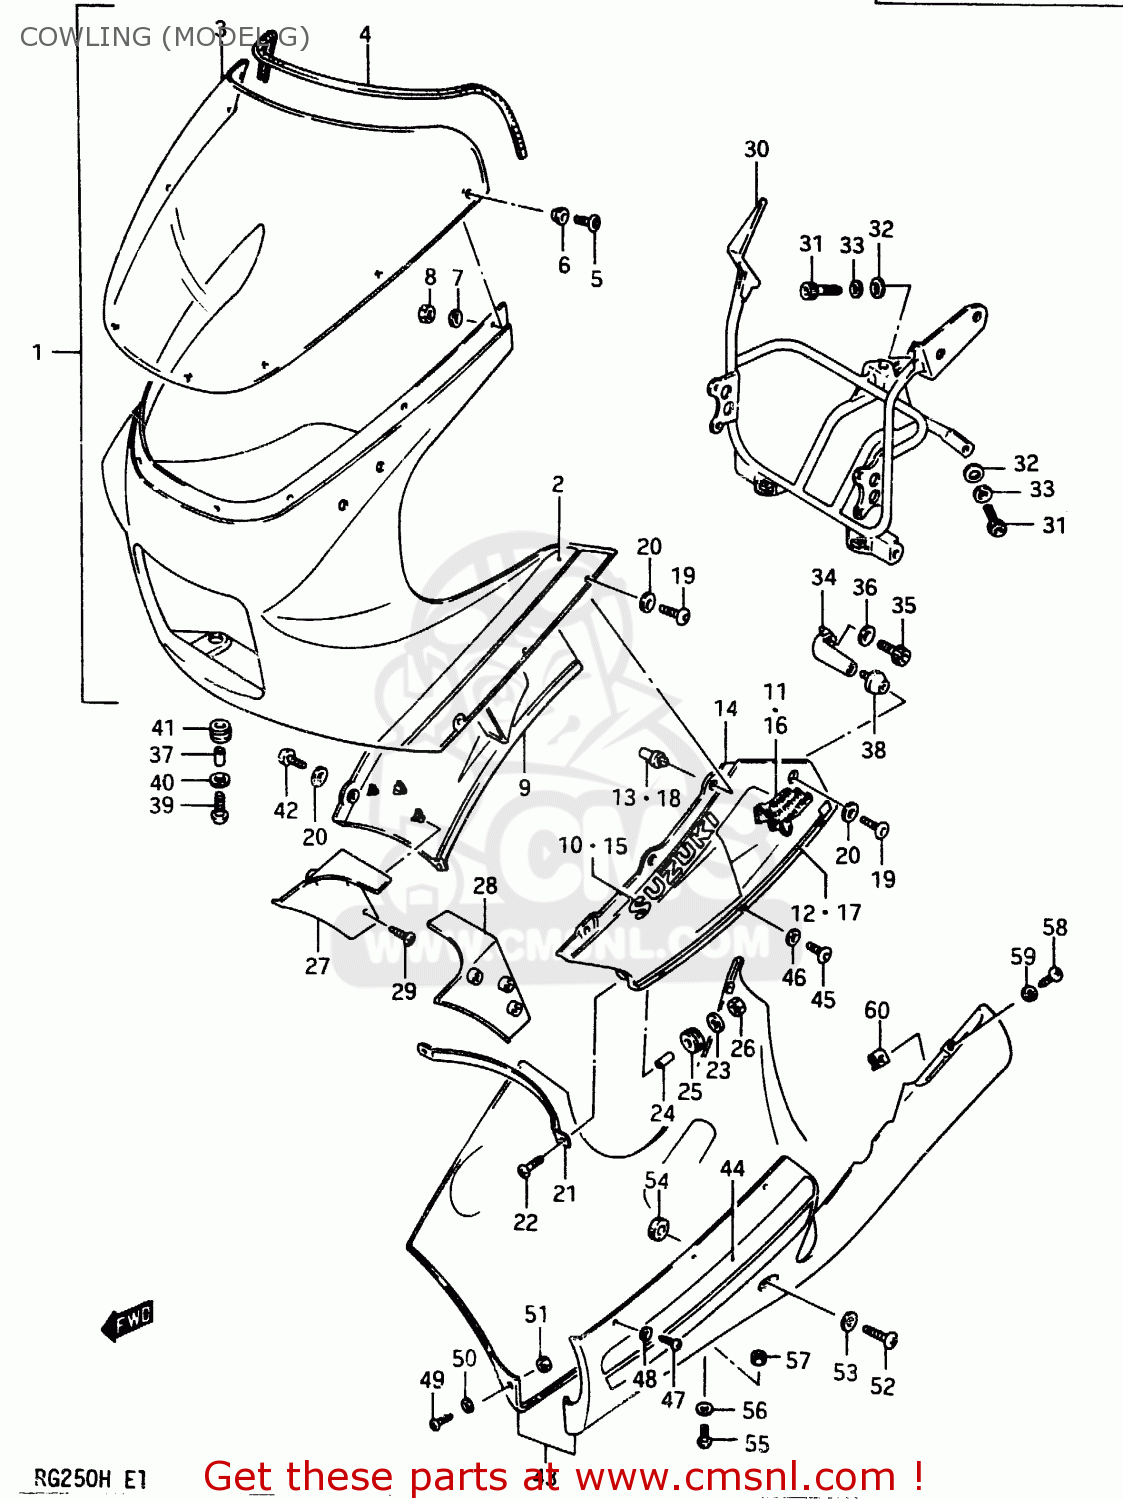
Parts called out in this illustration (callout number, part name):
1	COWLING ASSY (WHITE)
2	TAPE SET
3	WINDOW
4	MOLDING
5	SCREW(5X14)
6	CUSHION
7	WASHER,5MM
8	NUT 8MM
9	COVER, COWLING RH (RED)
10	EMBLEM,FUEL TA
11	EMBLEM
12	TAPE SET, SIDE RH
13	NUT,COWLING COVER
14	COVER, COWLING LH (RED)
15	EMBLEM,FUEL TA
16	EMBLEM
17	TAPE SET, SIDE LH
18	NUT,COWLING COVER
19	SCREW(6X20)
20	WASHER(6.5X16X1.2)
21	PANEL, COWLING LOWER (RED)
22	SCREW
23	WASHER (6.5X20X1.2)
24	SPACER (6.8X10X10)
25	CUSHION
26	NUT 6MM
27	GUIDE PLATE, RH
28	GUIDE PLATE, LH
29	SCREW
30	BRACE, COWLING
31	BOLT
32	WASHER
33	WASHER,LOCK,8.
34	SPACER, COWLING LOWER
35	BOLT
36	WASHER
37	SPACER(6.5X11.5X12)
38	CUSHION,COWLING
39	SCREW(6X20)
40	WASHER
41	CUSHION
42	SCREW(6X30)
43	COWLING, UNDER
44	TAPE SET, UNDER
45	SCREW(6X12)
46	WASHER(6.5X16X1.2)
47	SCREW
48	WASHER
49	SCREW
50	WASHER
51	NUT
52	SCREW
53	WASHER(6.5X16X1.2)
54	SPACER,UNDER COWLING
55	SCREW
56	WASHER (5.5X14X1.2)
57	NUT
58	SCREW
59	WASHER
60	NUT
